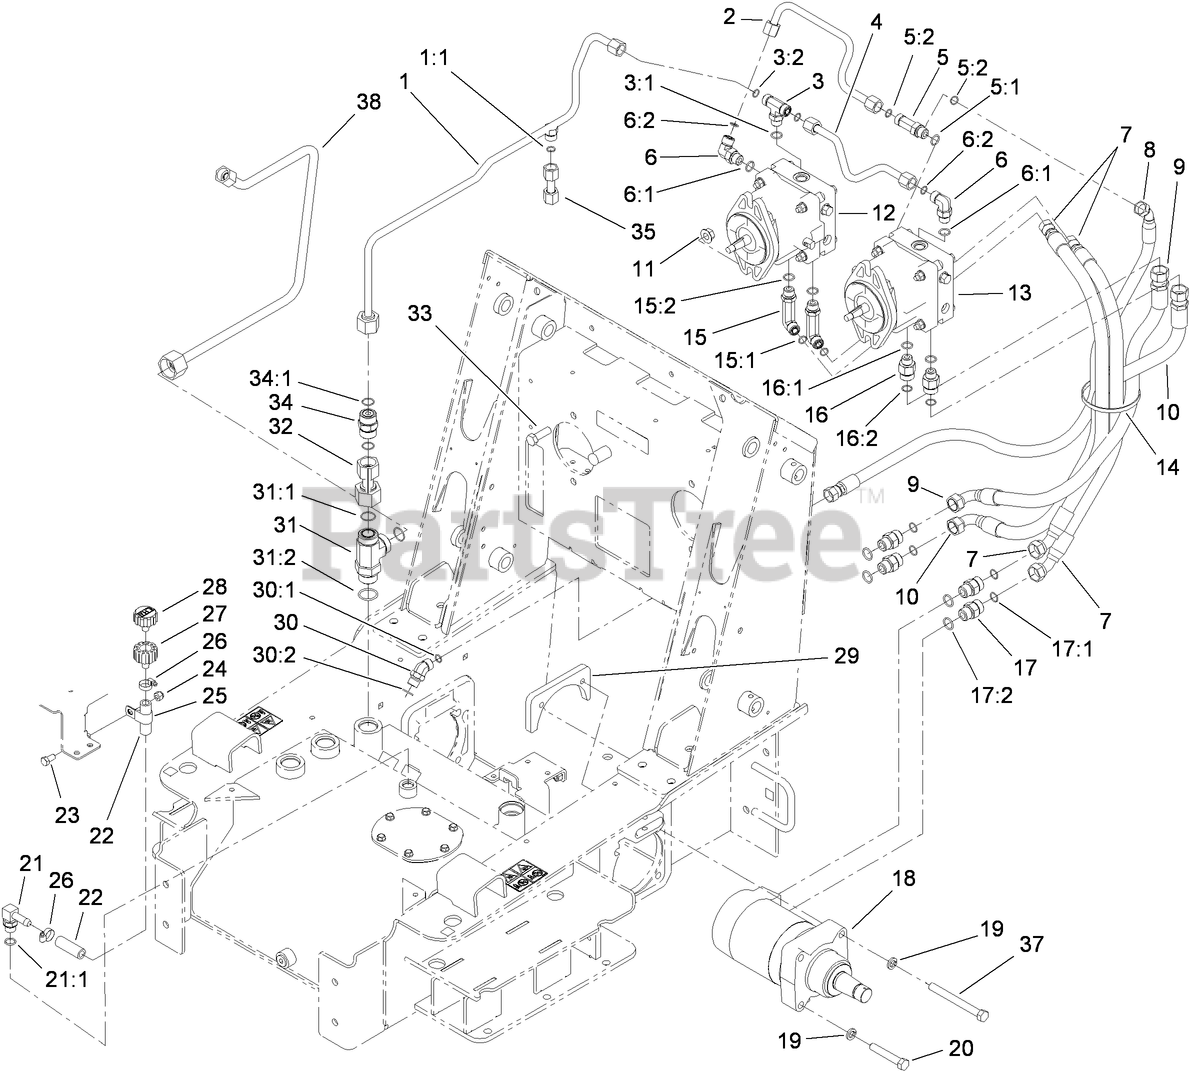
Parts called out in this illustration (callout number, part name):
1	HYD TUBE ASM
1:1	O-RING
2	TUBE-HYD
3	FITTING-HYD, TEE
3:1	O-RING
3:2	O-RING
4	TUBE-HYD
5	FITTING-TEE
5:1	O-RING
5:2	O-RING
6	FITTING-ELBOW-90 DEG
6:1	O-RING
6:2	O-RING
7	HOSE-HYD
8	HOSE-HYD
9	HOSE-HYD
10	HOSE-HYD
11	NUT-LOCK, FLANGE
12	RH HYD PUMP ASM
13	LH HYD PUMP ASM
14	TIE-CABLE
15	FITTING-ELBOW, 90 DEG
15:1	O-RING
15:2	O-RING
16	FITTING-STR
16:1	O-RING
16:2	O-RING
17	FITTING-STRAIGHT
17:1	O-RING
17:2	O-RING
18	HYD MOTOR ASM
19	WASHER-LOCK
20	SCREW-HH, TAP
21	FITTING-ELB 90
21:1	O-RING
23	SCREW-HHF
24	NUT-LOCK, NI
25	CLAMP-R
26	CLAMP-HOSE
27	ADAPTER-BREATHER
28	BREATHER
29	PLATE-MOUNTING
30	FITTING-HYD, 45 DEG
30:1	O-RING
30:2	O-RING
31	FITTING-TEE
31:1	O-RING
31:2	O-RING
32	TUBE-HYD
33	SCREW-HH
34	HYD CHECK VALVE ASM
34:1	O-RING
35	TUBE-HYD
37	SCREW-HH
38	TUBE-HYD
